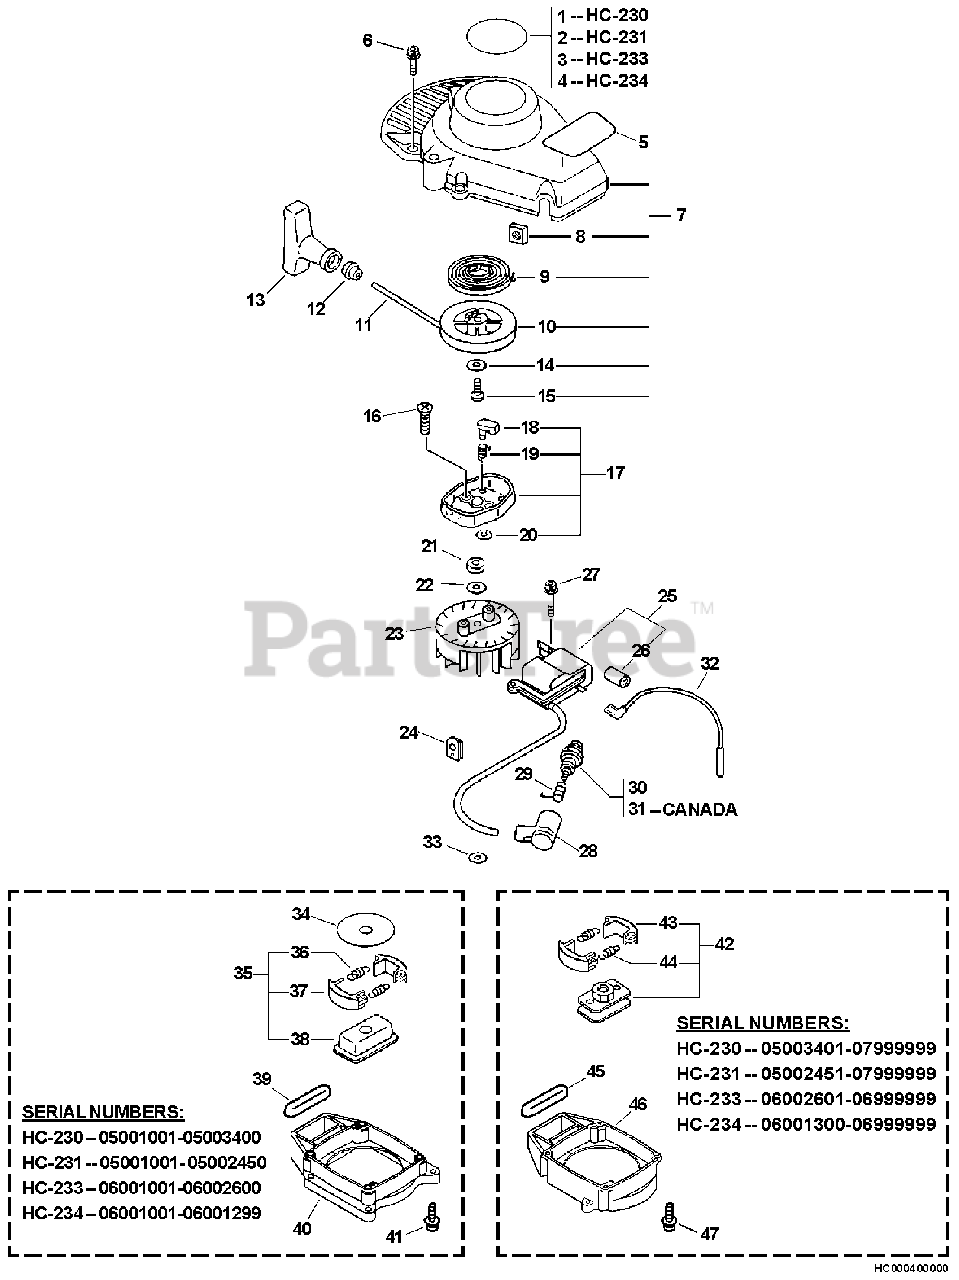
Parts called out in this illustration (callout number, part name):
1	LABEL, MODEL
2	LABEL, MODEL
3	LABEL, MODEL
4	LABEL, MODEL
5	LABEL, CAUTION - ISO
6	BOLT 5×16
7	STARTER, RECOIL
8	NUT M5
9	SPRING, RECOIL
10	REEL, ROPE
11	ROPE, STARTER 3×800
12	GUIDE, ROPE
13	GRIP, STARTER
14	WASHER
15	SCREW
16	SCREW 6×14
17	PULLEY ASSY, STARTER
18	PAWL, STARTER
19	SPRING, RETURN
20	E-RING 4
22	WASHER 8.5×16×1.2
23	FLYWHEEL
25	COIL, IGNITION
26	TUBE, INSULATOR
27	BOLT 5×16
28	CAP, SPARK PLUG
29	TERMINAL, SPARK PLUG
30	SPARK PLUG - BPM8Y
31	SPARK PLUG - BPMR8Y
32	LEAD - GROUND
33	WASHER, CLUTCH
34	PLATE, CLUTCH
35	CLUTCH ASSY
36	SPRING, CLUTCH
37	SHOE, CLUTCH
38	HUB, CLUTCH
39	CUSHION, FUEL TANK
40	CASE, CLUTCH
41	BOLT 4×14
42	CLUTCH ASSY
43	SHOE, CLUTCH
44	SPRING, CLUTCH
45	CUSHION, FUEL TANK
46	CASE, CLUTCH
47	BOLT 4×14
